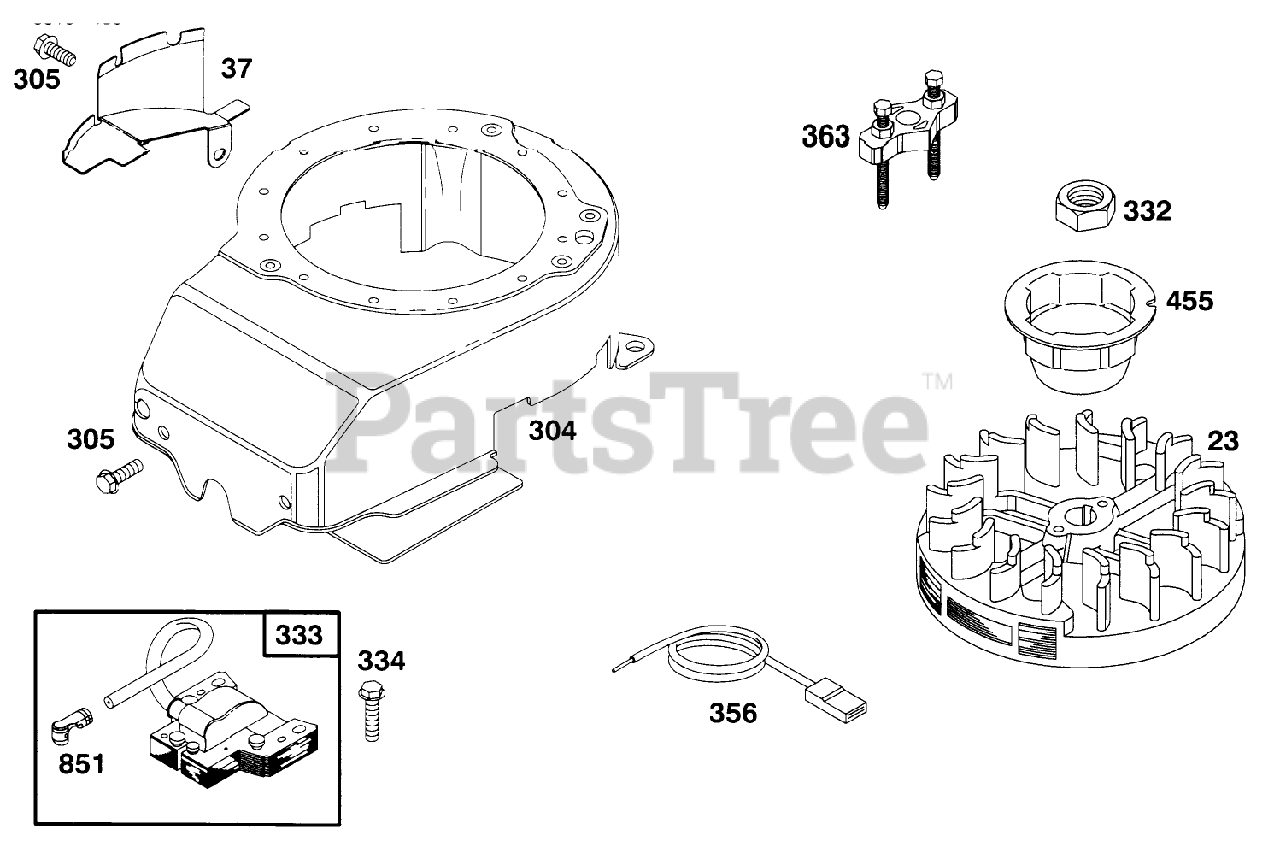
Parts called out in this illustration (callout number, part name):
23	Flywheel
37	Flywheel Guard
304	Housing-Blower
305	Screw-Hex
333	Armature-Magneto
334	Screw-Sem
356	Wire Stop
363	Puller-Flywheel
851	Terminal-Spark Plug
